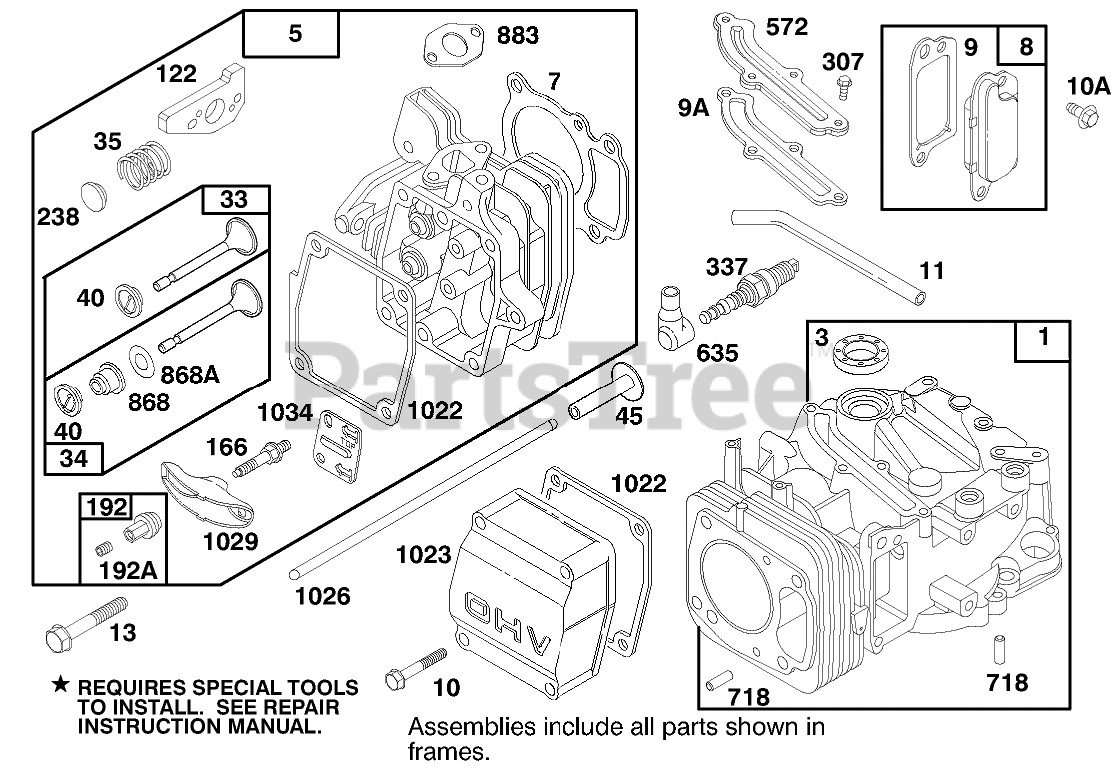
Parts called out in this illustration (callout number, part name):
1	CYLINDER ASSEMBLY
3	SEAL - OIL
5	CYLINDER HEAD
7	CYLINDER HEAD GASKET
8	BREATHER ASM
9	BREATHER GASKET
9A	GASKET-BREATHER
10	HEX HEAD SCREW
10A	HEX HEAD SCREW
11	TUBE - BREATHER
13	CYLINDER HEAD SCREW
33	EXHAUST VALVE
34	INTAKE VALVE
35	VALVE SPRING
40	SPRING RETAINER
45	VALVE TAPPET
122	ADAPTER ASSEMBLY
166	ROCKER ARM STUD
192	Ball & Screw-Rocker Arm (Incl. Ref. #192A)
192A	Screw-Set
238	VALVE CAP
307	SCREW - SEM
337	PLUG-SPARK
572	BAFFLE - CYCLINDER
635	SPARK PLUG ELBOW
718	DOWEL - SLEEVE
868	SealAssy-Valve
868A	Seal-Valve
883	EXHAUST GASKET
1022	ROCKER COVER GASKET
1023	COVER - VALVE
1026	PUSH ROD
1029	ROCKER ARM
1034	PUSH ROD GUIDE
